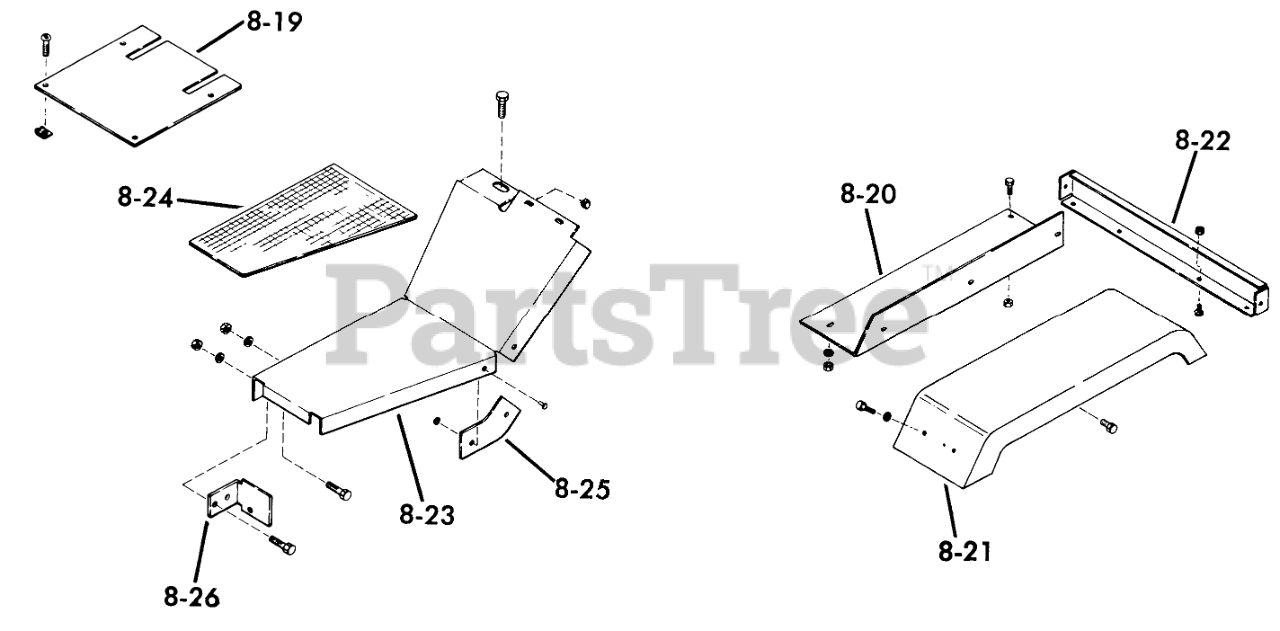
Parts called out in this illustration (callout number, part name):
8-01	Asy-Grille Shroud
8-02	Light Bracket
8-02	Bolt
8-02	Nut
8-03	ROD-GRILLE
8-03	Nut
8-04	SPRING GRILLE
8-05	ANGLE-GRILLE
8-05A	ANGLE-GRILLE
8-05A	SCREW
8-06	Spacer
8-07	Spacer
8-08	Cover-Front
8-08	BOLT
8-08	NUT
8-08A	Cover
8-08A	Bolt-Hex
8-08A	Nut
8-10	Assy-Hood
8-10	INSULATION FOAM
8-10	Latch
8-10	RIVET
8-11	Bushing
8-11	HHCS
8-11	Nut
8-11	WASHER 5/16 SAE
8-12	Edge Trim
8-12	Control Housing
8-12	GROMMET
8-12	SCREW
8-13	Plate Screws
8-13	Right Differential Gear
8-13	Plate-Instrument
8-14	Plate
8-15	Plate Screws
8-15	PLUG BUTTON
8-15	Plate-Rear Instrument
8-15	Speed Nut
8-15	Screw
8-16	Panel
8-16	Screw
8-17	Panel-Console RH
8-17	Panel-Console LH
8-17	SCREW
8-18	Battery Support
8-18	Battery Bracket
8-18	SCREW
8-19	Access Cover Plate
8-19	Speed Nut
8-19	Screw-Hex HD Slotted
8-19	LOCKWASHER
8-20	Plate-Fender RH
8-20	Plate-Fender LH
8-20	Bolt
8-20	Nut
8-21	Fender
8-21	Bolt
8-21	Nut
8-21	WASHER 5/16 SAE
8-22	Wear Plate
8-22	Channel
8-22	GROMMET
8-22	Bolt
8-22	Screw
8-22	Nut
8-23	Footrest RH
8-23	Footrest LH
8-23	Nut
8-24	Footrest Mat RH
8-24	Footrest Mat LH
8-25	Filler Plate
8-25	WASHER
8-25	RIVET
8-26	Bracket
8-26	BOLT
8-26	Washer
